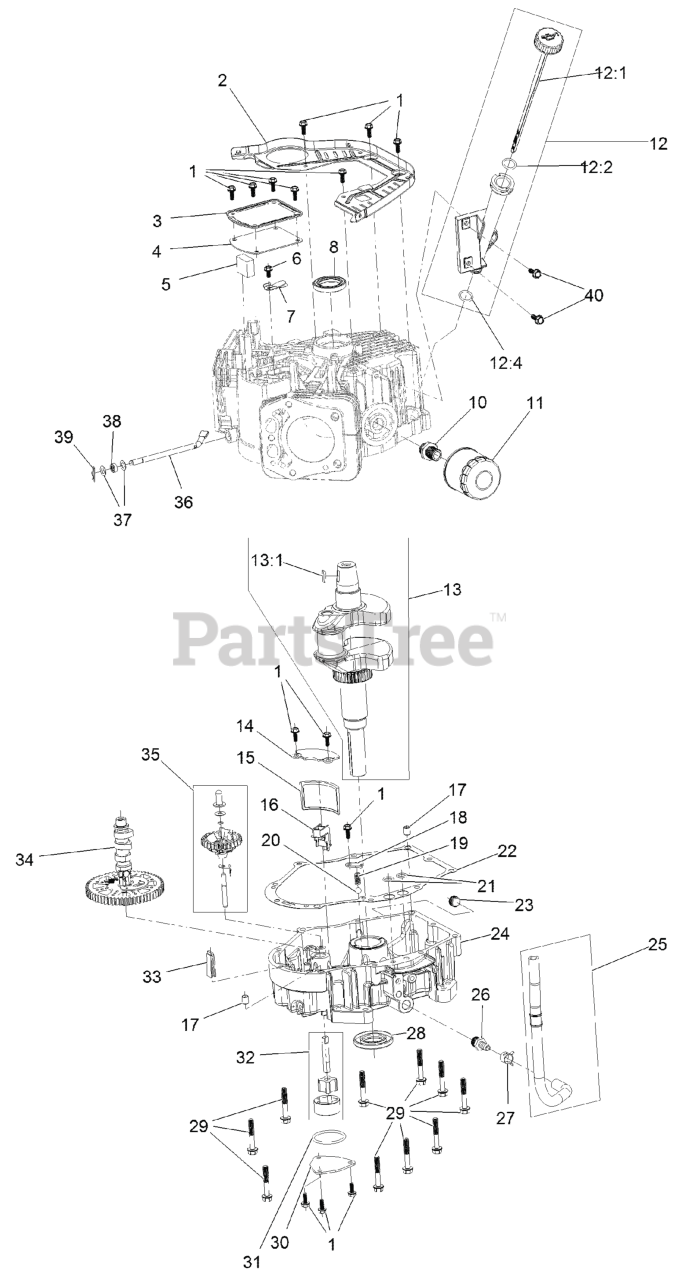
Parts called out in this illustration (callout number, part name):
1	SCREW-HHF
3	COVER-BREATHER
4	GASKET-BREATHER
5	FILTER-BREATHER
6	SCREW-HHF
7	VALVE-BREATHER
8	SEAL-OIL
10	ADAPTOR-FILTER, OIL
11	FILTER-OIL
12	OIL TUBE ASM
12:1	DIPSTICK
13	CRANKSHAFT
13:1	KEY-WOODRUFF
14	COVER-SCREEN, OIL
15	SCREEN-OIL
16	RETAINER-SCREEN
17	PIN-DOWEL
18	PLATE-RETAINER
20	VALVE-BALL
22	GASKET-COVER, CRANKCASE
23	PLUG-DRAIN
24	COVER-CRANKCASE
25	OIL DRAIN HOSE ASM
26	FITTING-HOSE
27	CLAMP-HOSE
29	SCREW-HHF
30	COVER-OIL PUMP
32	OIL PUMP ASM
33	DEFLECTOR-OIL, RUBBER
34	CAMSHAFT
35	GOVERNOR ASM
36	SHAFT-GOVERNOR
37	WASHER-PLAIN
38	SEAL-OIL
39	PIN-HAIR
40	SCREW-HHF
